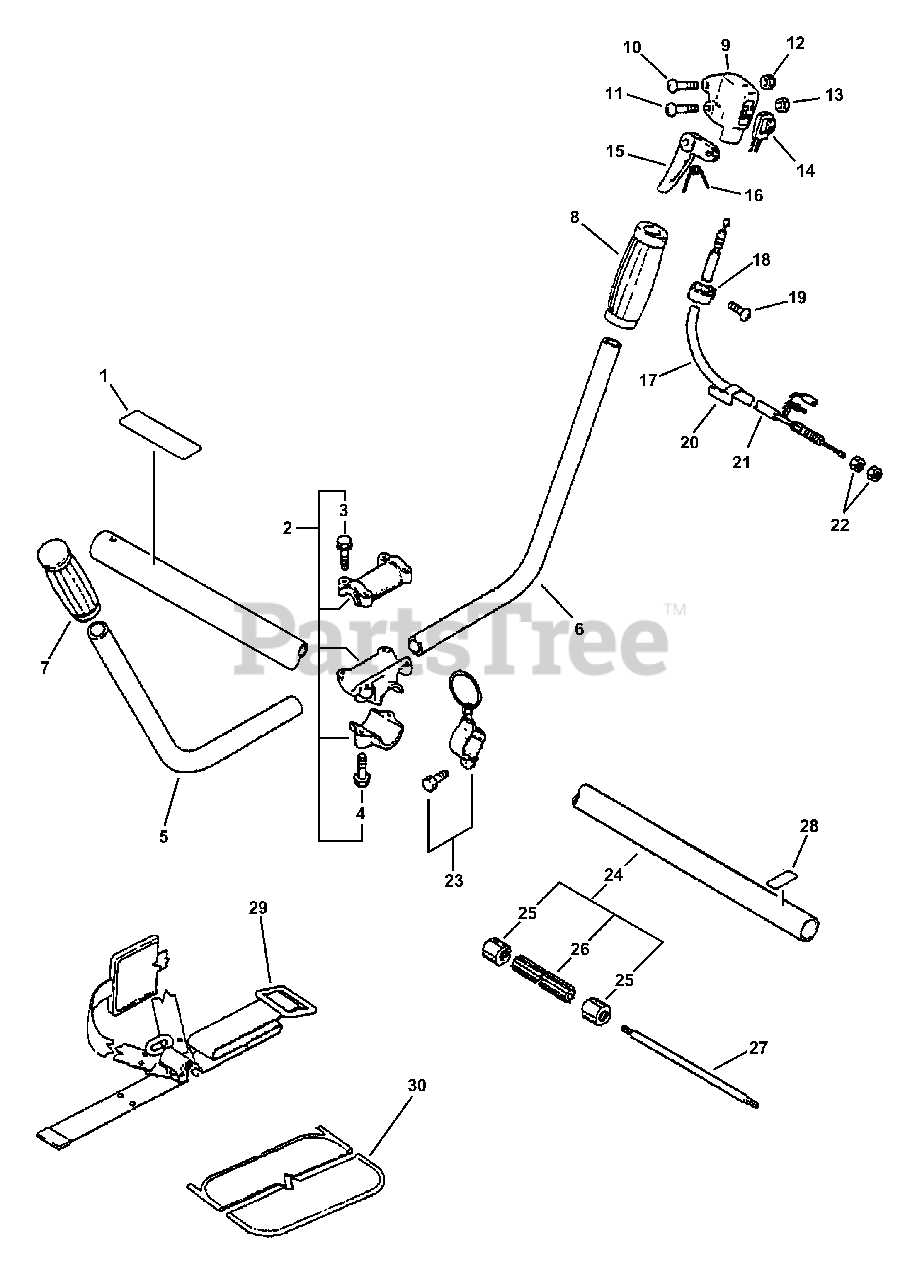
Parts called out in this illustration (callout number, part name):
1	LABEL - CAUTION
2	HANDLE BRACKET KIT
3	BOLT - 5X25
4	BOLT - 6X30
5	HANDLE, FRONT - LEFT
6	HANDLE
7	GRIP, HANDLE - LEFT
8	GRIP, HANDLE
9	BRACKET, THROTTLE CONTROL
10	SCREW - 5X25
11	SCREW - 5X30
12	LOCKNUT - 5
13	NUT - 5
14	IGNITION SWITCH ASSY
15	TRIGGER, THROTTLE
16	SPRING, TRIGGER
17	CABLE, THROTTLE
18	CLAMP
19	SCREW - 5X10
20	BRACKET
21	TUBE
22	LOCKNUT - 6
23	HANGER KIT
24	MAIN PIPE ASSY
25	BUSHING
26	LINER - FLEXIBLE
27	DRIVESHAFT - FLEXIBLE
28	LABEL - ALIGNMENT
29	SHOULDER STRAP ASSY
30	CUSHION
